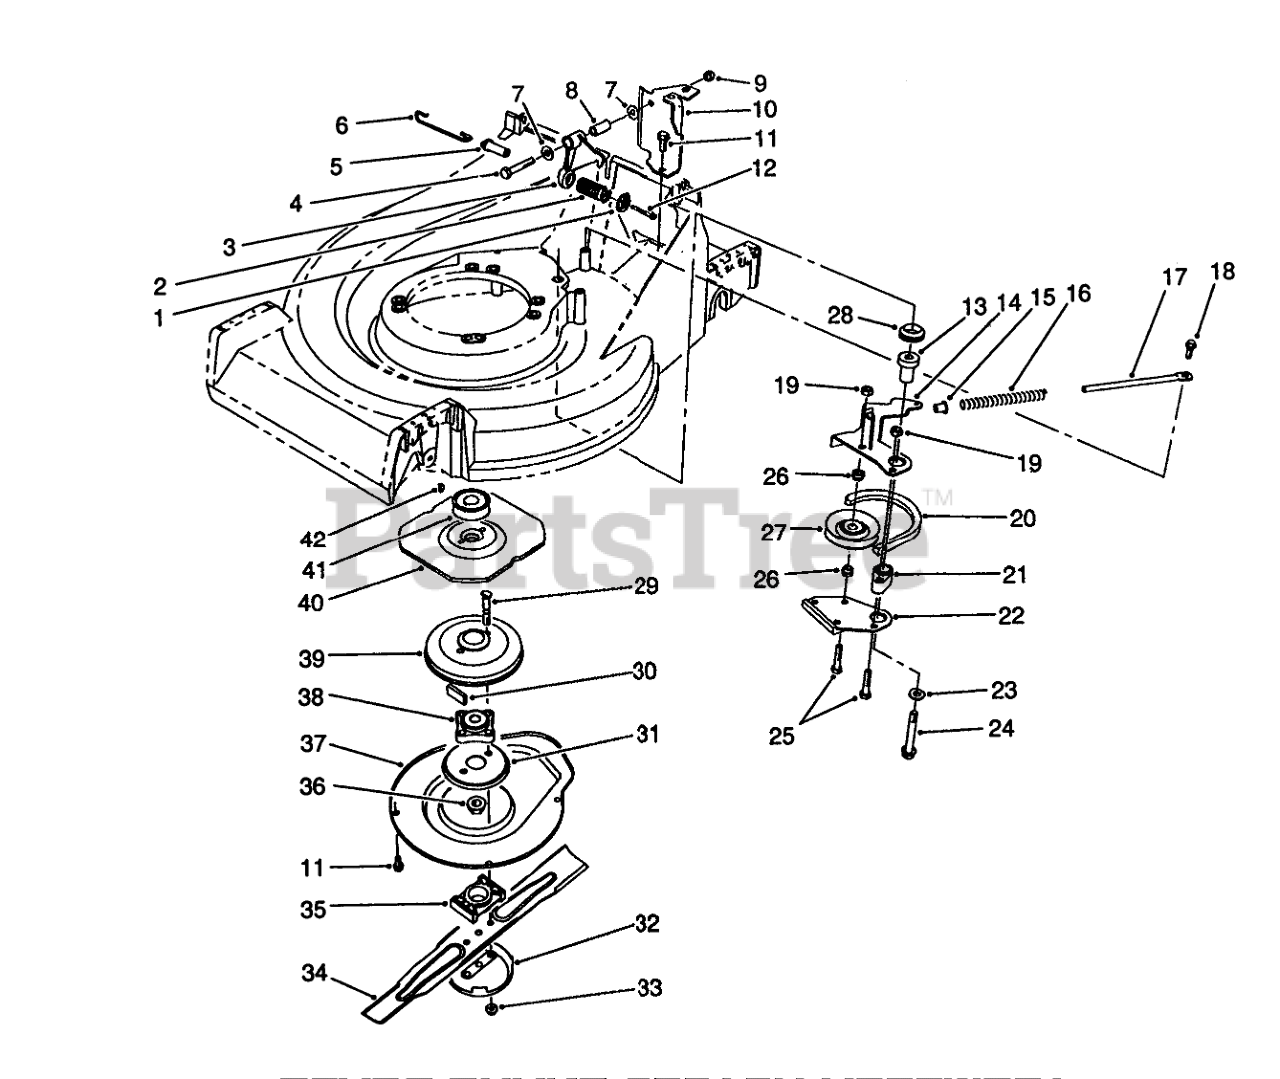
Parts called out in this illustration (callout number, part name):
1	RETAINER-SPRING
2	COMPRESSION SPRING
3	CRANK
4	SCREW-HH
5	SPRING PIN
6	CONTROL LINK
7	WASHER-PLAIN
8	STRAIGHT BUSHING
10	Bracket-Cable Support
11	SCREW-HWHTF
12	SCREW-HWHTF
13	BBC PM BUSHING
14	Lever
15	SPACER
16	COMPRESSION SPRING
17	SPRING ROD
18	SCREW-SHOULDER
19	NUT-LOCK, NI
20	V-BELT
21	BRAKE PLATE HUB
22	BRAKE SHOE
23	WASHER-PLAIN
24	3/8-16 X 2-3/4 CAPSCR
25	SCREW-HH
26	IDLER PULLEY HUB
27	PULLEY-IDLER
28	V-RING SEAL
29	BOLT-BLADE
30	DAMPENER-VIBRATION
31	Screen-BBC
32	Anti Scalp Cup
33	NUT-LOCK
34	Key
35	SPACER-BLADE
36	NUT-LOCK, NI
37	Cover
38	HUB ASM
39	BRAKE DRUM
40	FLYWHEEL - BBC
41	PULLEY
42	KEY-WOODRUFF
